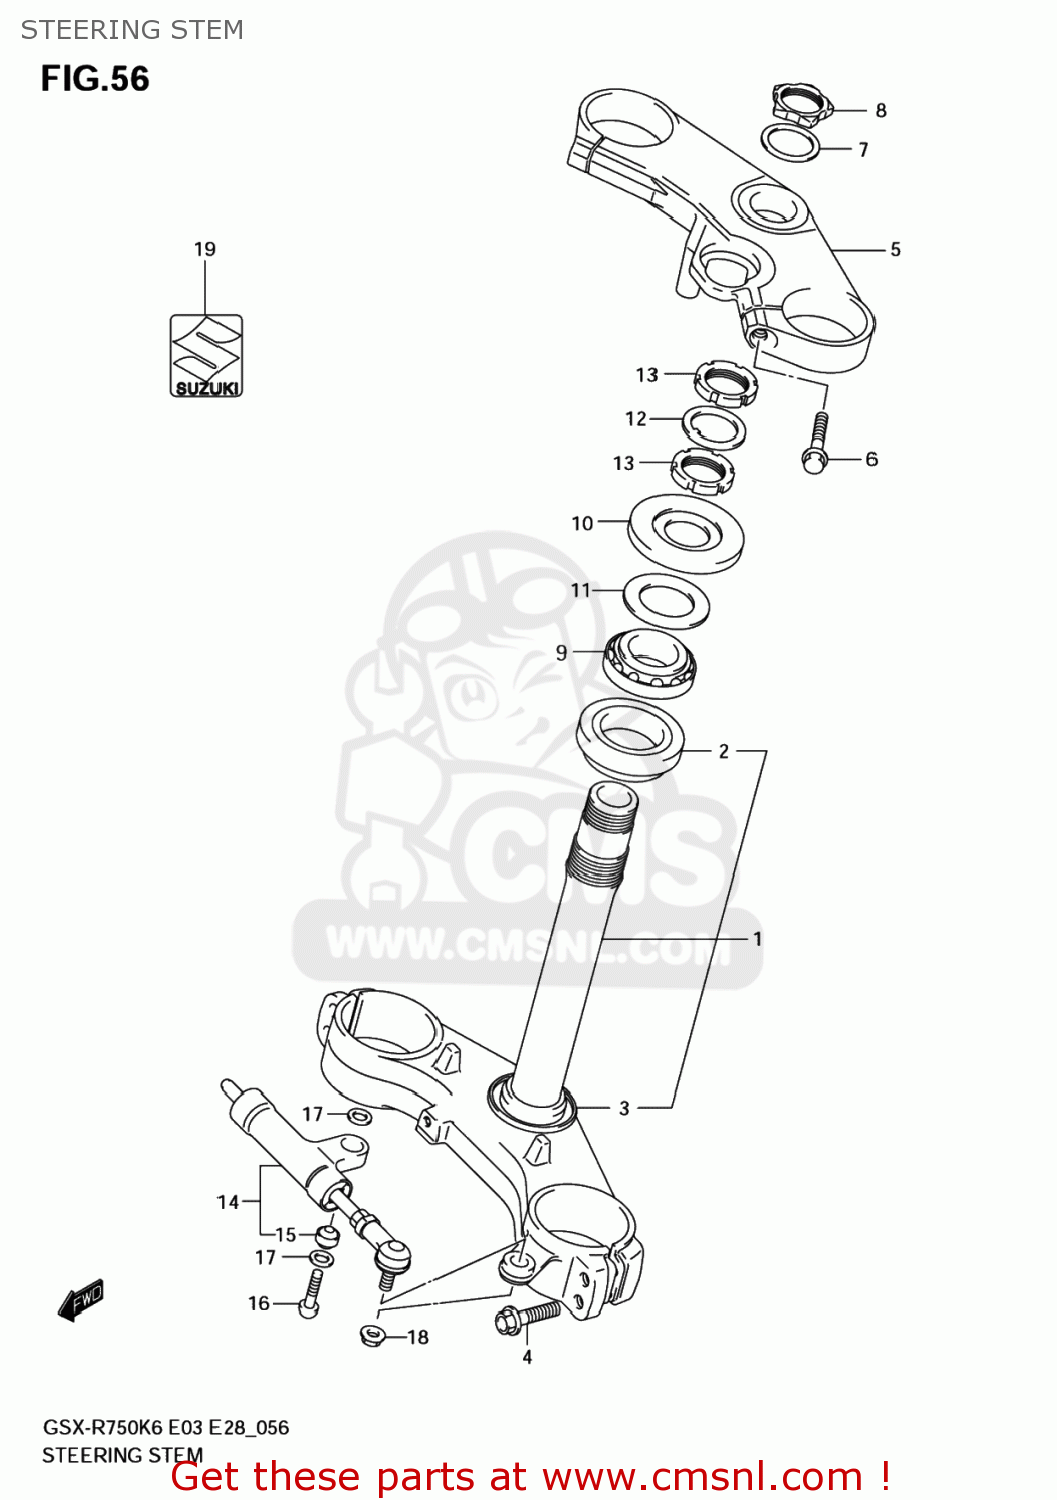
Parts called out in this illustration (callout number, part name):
1	STEM,STEERING
2	BEARING(30X55X17)
3	SEAL,STEERING LWR
4	BOLT,HOLDER AXLE(8X40)
5	HEAD,STEERING STEM
6	BOLT
7	WASHER,STEM HEAD
8	NUT,STEM HEAD
9	BEARING(30X55X17)
10	SEAL, STEM UPPER DUST
11	SEAL,STEERING LWR
12	WASHER, STEM
13	NUT,STEERING STEM
14	DAMPER ASSY,STEERING
15	BEARING(8X17.5X11)
16	BOLT (8X35)
17	SEAL,PILLOW BALL,DUST
18	NUT
19	EMBLEM,S
